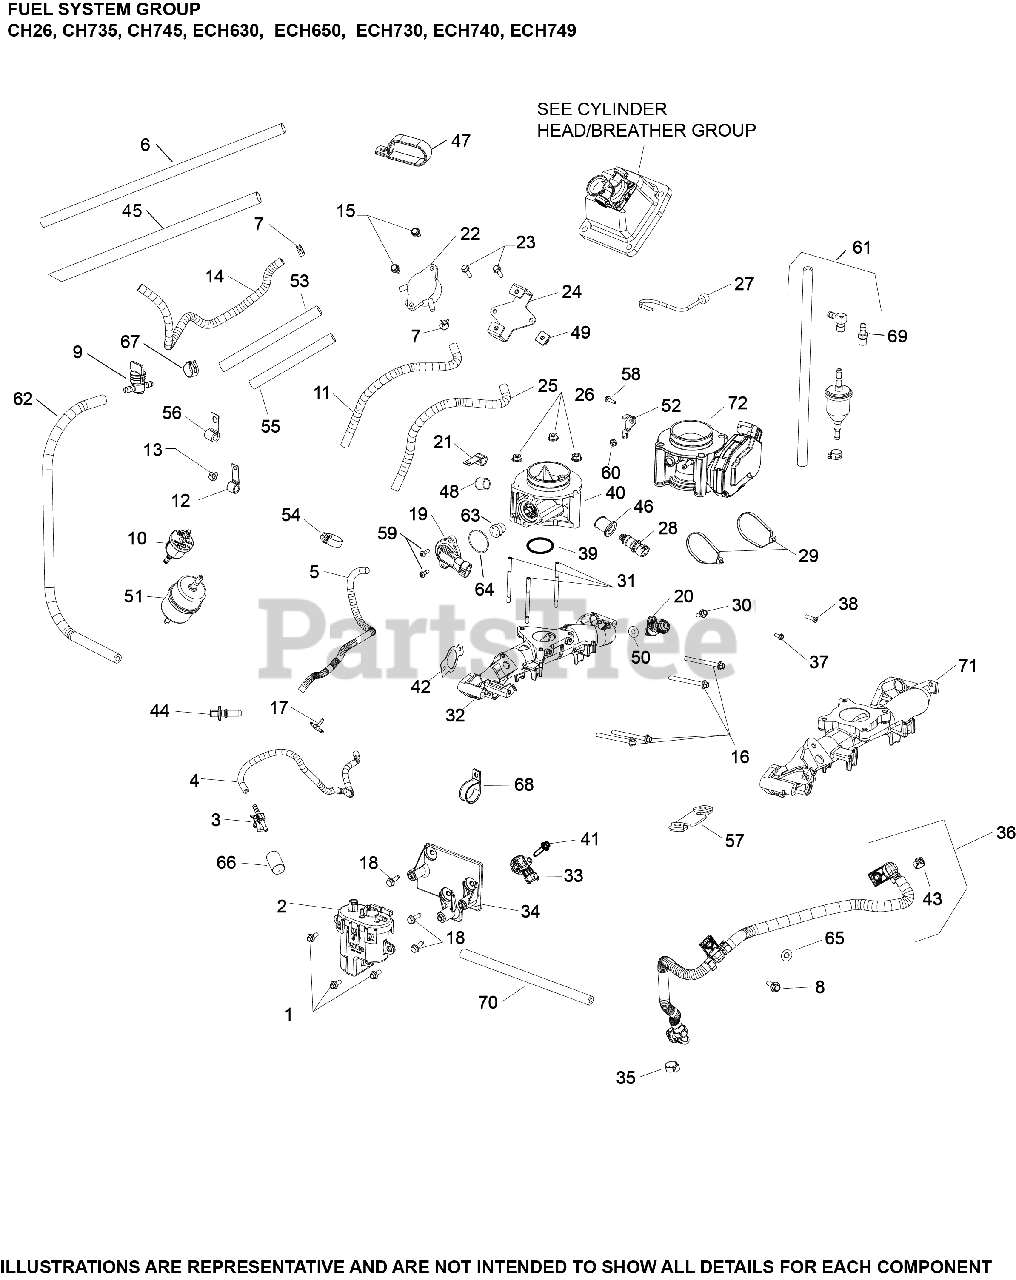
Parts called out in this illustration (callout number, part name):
1	SCREW, FLG M6X1.0X16
2	PUMP, FUEL MODULE
4	HOSE, EVAPORATIVE (15.0)
5	SLEEVE, ANTI-ABRASION
7	CLAMP, HOSE (KM)-USE 25 237 31-S
8	SCREW, FLG M6x1.0x20
10	FILTER, FUEL
11	HOSE,LW PERM.FUEL 24.00"-USE 25 111 81-S
16	SCREW, FLG M6X1.0X60
17	TEE CONNECTOR
18	SCREW, THREAD FORMING
19	SENSOR, THROTTLE POSITION
20	INJECTOR, FUEL
21	CLIP, CABLE
31	STUD,M6X1.0X84
32	KIT, MANIFOLD
33	SENSOR, T-MAP
34	BAFFLE, FUEL MODULE
35	CLAMP, HOSE
36	RAIL, FUEL ASSEMBLY (HORIZONTAL COMMAND)
40	BODY, THROTTLE ASM (30)
42	GASKET, INTAKE MANIFOLD USE 24 041 79-S
43	CLAMP, OETIKER
48	CAP, MASKING
50	KIT, FUEL INJECTOR O-RING
55	SLEEVE, ANTI ABRASION-USE 25 431 12-S
63	MAGNET ASSEMBLY, TPS
64	O-RING, TPS SENSOR
65	CLIP, RETAINER
